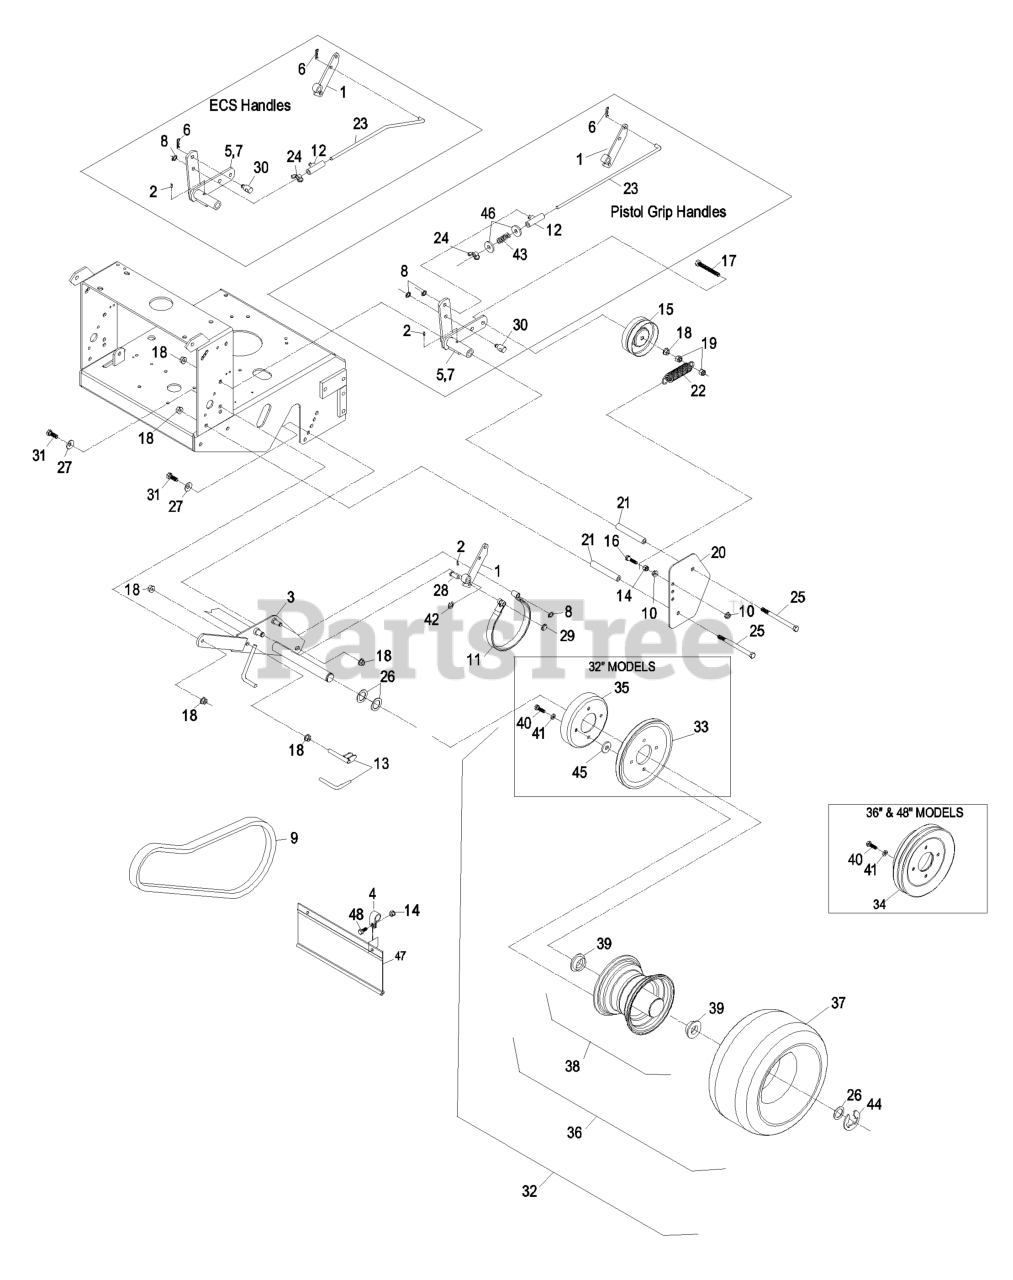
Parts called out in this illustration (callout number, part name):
1	ARM-BRAKE
2	FITTING-GREASE
3	AXLE
4	CLAMP-R
6	PIN-COTTER
8	RING-RETAINING
9	BELT,WHEEL DRIVE
11	BAND-BRAKE
12	SWIVEL-BRAKE
13	SCRAPER
14	NUT-LOCK, NI
15	IDLER-WHEEL, DRIVE
16	SCREW-HH
17	SCREW-HH
18	NUT-HHF, WHIZ
19	NUT-LOCK, NI
20	SHIELD-WHEEL, DRIVE
21	SPACER-SHIELD
22	SPRING-EXTENSION
23	LINKAGE-BRAKE
24	WINGNUT-NYLOCK
25	SCREW-HH
26	WASHER-SPACER
27	WASHER-BELLEVILLE
28	PIN-CLEVIS
29	RING-RETAIN,PUSH,EXT,FLAT
30	SWIVEL-LEVER, DRIVE
31	SCREW-HH
32	DRIVE WHEEL ASM
33	SHEAVE-WHEEL, DRIVE
34	DRUM AND SHEAVE ASM
35	DRUM-BRAKE
36	WHEEL AND TIRE ASM
37	TIRE-TURFMASTER
38	WHEEL AND HUB ASM
39	BEARING-FLANGED
40	SCREW-HH
41	WASHER-LOCK
42	RING-RETAINING, EXTERNAL
43	SPRING-COMPRESSION
44	RING-SNAP
45	WASHER
46	WASHER-PLAIN
47	SHIELD-TRAILING
48	SCREW-HH
